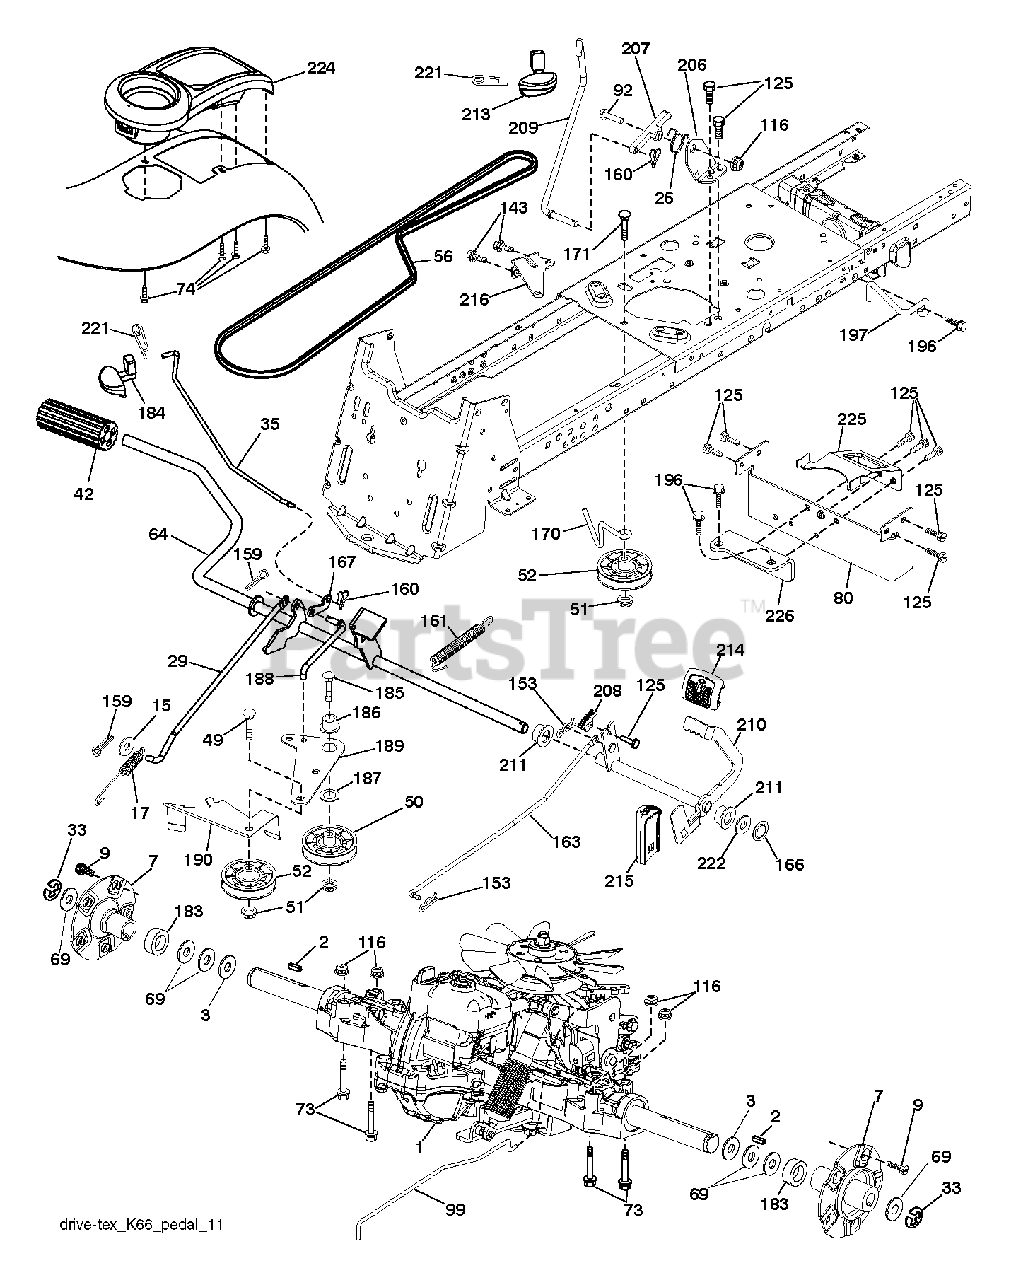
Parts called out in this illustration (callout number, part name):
3	WASHER T
7	\\B ASM. WHEEL
9	HUB BOLT
15	WASHER
17	SPRING.BRAKE.K46
26	SPRING.RETURN.CRUISE
29	ROD.BRAKE.K66
33	E RING HYT
35	ROD.BRKAE.PARKING.STEALTH
42	PEDAL COVER T
50	IDLER.FLAT.910.OFFSET
52	IDLER.V-GROOVE.910.OFFSET
64	SHAFT.ASM.PEDAL.BRK.CN
73	BOLT HEX 5/16-18 GR 5
74	SCREW,HEX
80	STRAP.TORQUE.K66
99	ROD.SPRING.BYPASS.K66.GT.Z
116	NUT LOCK HEX FLANGE 5/16-18
125	SCREW
143	SCREW LT
159	COTTER PIN
160	RETAINER CLIP
161	SPRING, RETURN LT
163	ROD.PEDAL.CONTROL
166	NUT.PUSH.625
167	LATCH BRAKE PARKING
170	KEEPER.V-IDLER.CENTER.
183	SPACER.AXLE.HG.TEX
186	SPACER.RETAINER
188	LINK.CLUTCH.GROUND DRI
189	BELLCRANK.GRDDRIVE.NST
190	KEEPER.BELLCRANK.DRIVE
196	SCREW 3/8-16X1
197	BRKT.ANIT-ROTATION.CLU
206	BRKT.MOUNT.LATCH.CRUIS
207	LATCH.CONTROL.CRUISE
208	GEAR.SECTOR.CONTROL.CR
209	ROD.CONTROL.CRUISE.STE
210	ROCKER.ASM.PEDAL.CONTR
211	BEARING RER
213	KNOB.CONTROL.CRUISE
214	PAD PEDAL FORWARD
215	PEDAL.REVERSE.TEX.GT.4
216	BRKT.PULLEY.IDLER.WTEX
221	RETAINER.SPRING.CLIP.H
222	WASHER 21/32 X 1-1/4 X 10 GA.
225	KEEPER.BELT.TRANSAXLE.K66
226	BRACKET.MOUNT.TORQUE.K66.TG
